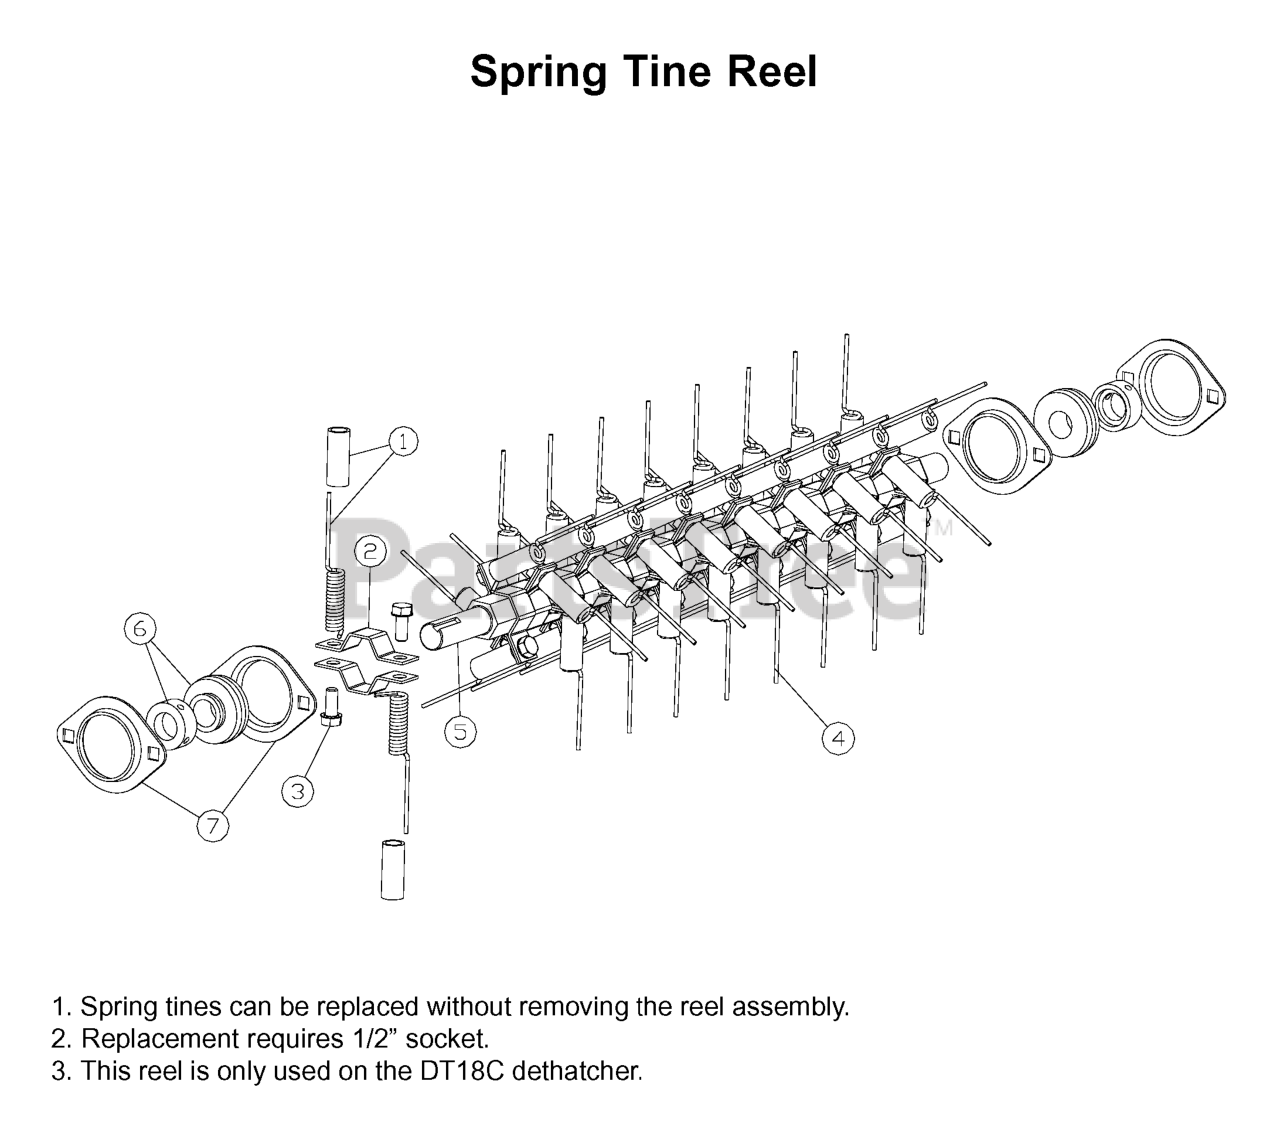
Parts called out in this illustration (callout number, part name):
1	SPRING TINE W/SLEEVE
2	CLAMP TINE PT# 491-011
4	TINE REEL ASSY
5	KIT, SHAFT TINE REEL
6	BEARING
7	STAMPING KIT
540054056	TINE REEL ASSY
